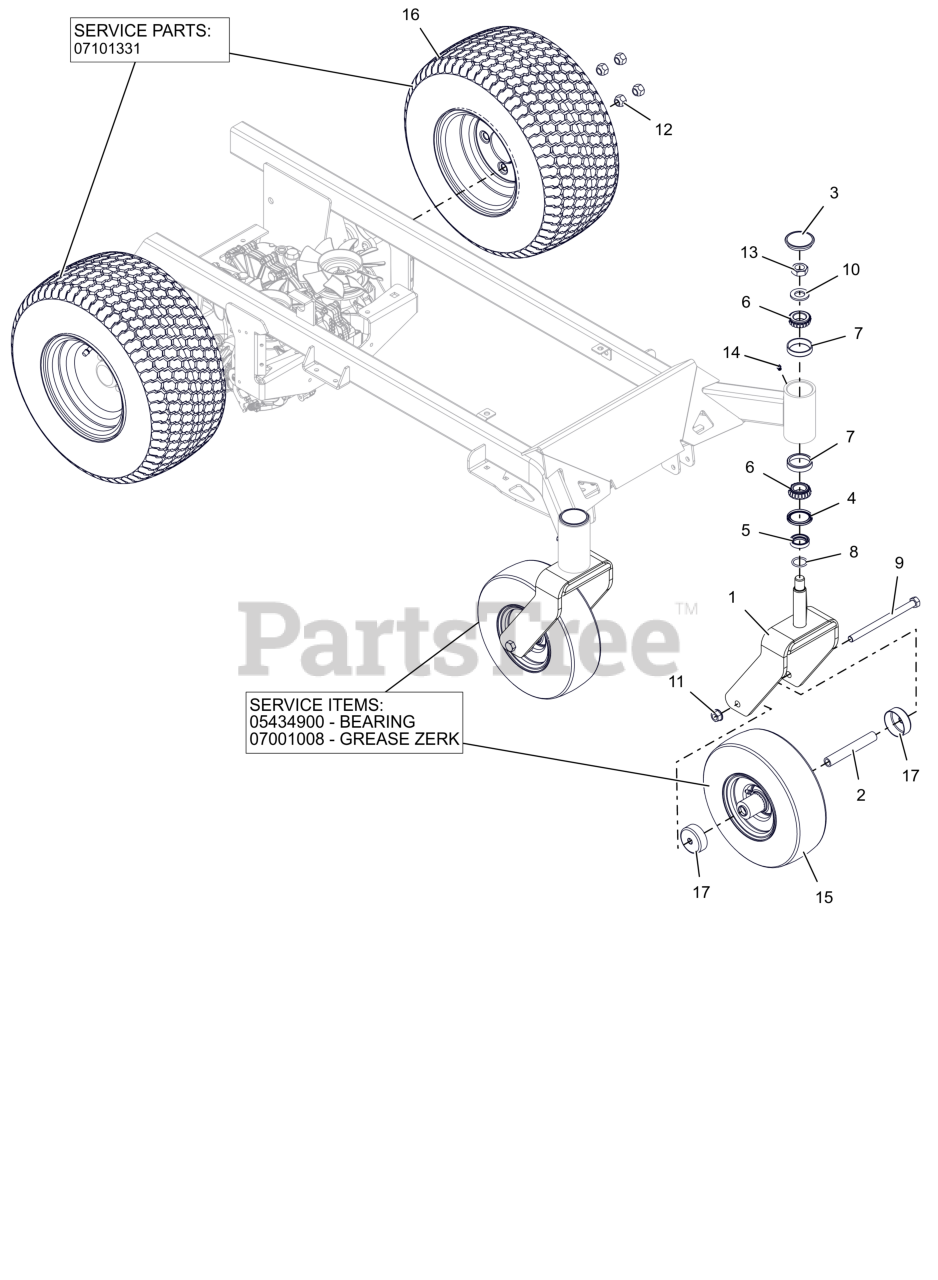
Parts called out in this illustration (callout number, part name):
1	WLDMT, CASTER FORK
2	SPACER, ROLLED WHEEL
3	CAP, DUST
4	BEARING SEAL 1.5 X 2 X .18
5	SPCR, CASTER FORK (1.00)
6	BRG-CONE 1.0X.58
7	BRG-CUP1.980X.420
8	O-RING 1.000X1.250X
9	BLT, HEX .50-13X7.00 G5 ZCC
10	WSHR, FLT .812X1.469X.134 ZCC
11	NUT-LK-CTR-FLG .500-13 GG ZCC
12	NUT, WHEEL .50-20 ZCC
13	NUT, JAM-TOP LK .750-16 ZCC
14	FTG, .25-28 FLUSH MNT GREASE
15	TIRE/WHEEL, 11 X 4-5
15	BRG-BALL .752X1.380X.500
15	1/4-28 EXTENDED GREASE FITTING
15	VALVE STEM ASS'Y
15	TIRE TUBE, 11/4.0-5 4 PLY TR87 90 BENT VALVE
16	ASSM TIRE\WHEEL, 18 X 8.50 - R8
16	TIRE, 18X8.50-R8
16	VALVE STEM ASS'Y
16	TIRE TUBE 18/6.50/8.50/9.50-8, 20/8.00/10.00-8 4 PLY TR13 STRAIGHT VALVE
17	SHIELD, WHEEL BEARING
